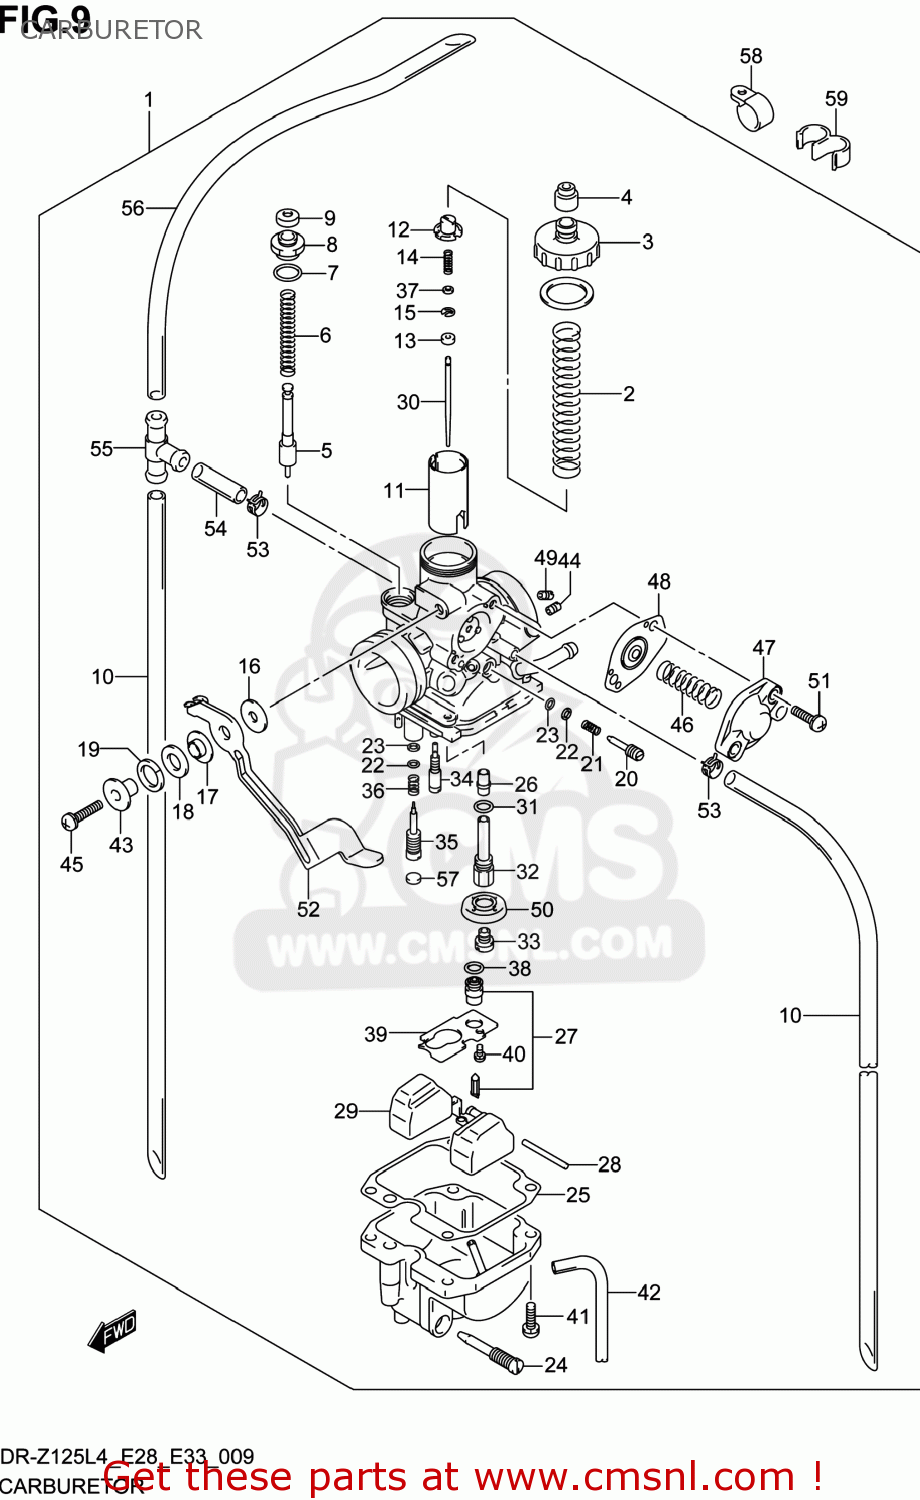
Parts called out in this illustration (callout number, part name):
1	CARBURETOR ASSY
2	SPRING
3	MIXING CAP ASSY
4	CAP
5	PLUNGER ASSY
6	SPRING
7	O RING
8	GUIDE SCREW,PLUNGER
9	CAP,STARTER VALVE
10	HOSE(5X8X475)
11	VALVE,PISTON
12	HOLDER
13	RING
14	SPRING
15	E RING
16	PLATE
17	RING
18	WASHER
19	WASHER,LOCK
20	SCREW,ADJUST
21	SPRING
22	WASHER
23	O RING,PILOT AIR SCREW
24	SCREW
25	GASKET (NAS)
26	JET,NEEDLE
27	VALVE ASSY,NEEDLE
28	PIN,FLOAT
29	FLOAT ASSY
30	JET,NEEDLE(5HGM74)
31	O RING
32	JET,HOLDER
33	JET,MAIN(102.5)
34	JET,PILOT(17.5)
35	ADJUSTER
36	SPRING
37	WASHER
38	O RING
39	PLATE
40	SCREW
41	SCREW
42	HOSE(3X5X650)
43	RING
44	JET,AIR(85.0)
45	SCREW
46	SPRING
47	COVER ASSY
48	DIAPHRAGM ASSY
49	JET,POWER(145)
50	HOLDER
51	SCREW
52	LEVER
53	CLIP
54	HOSE(5X8X25)
55	NIPPLE
56	HOSE(5X8X375)
57	PLUG
58	CLAMP
59	CLAMP
